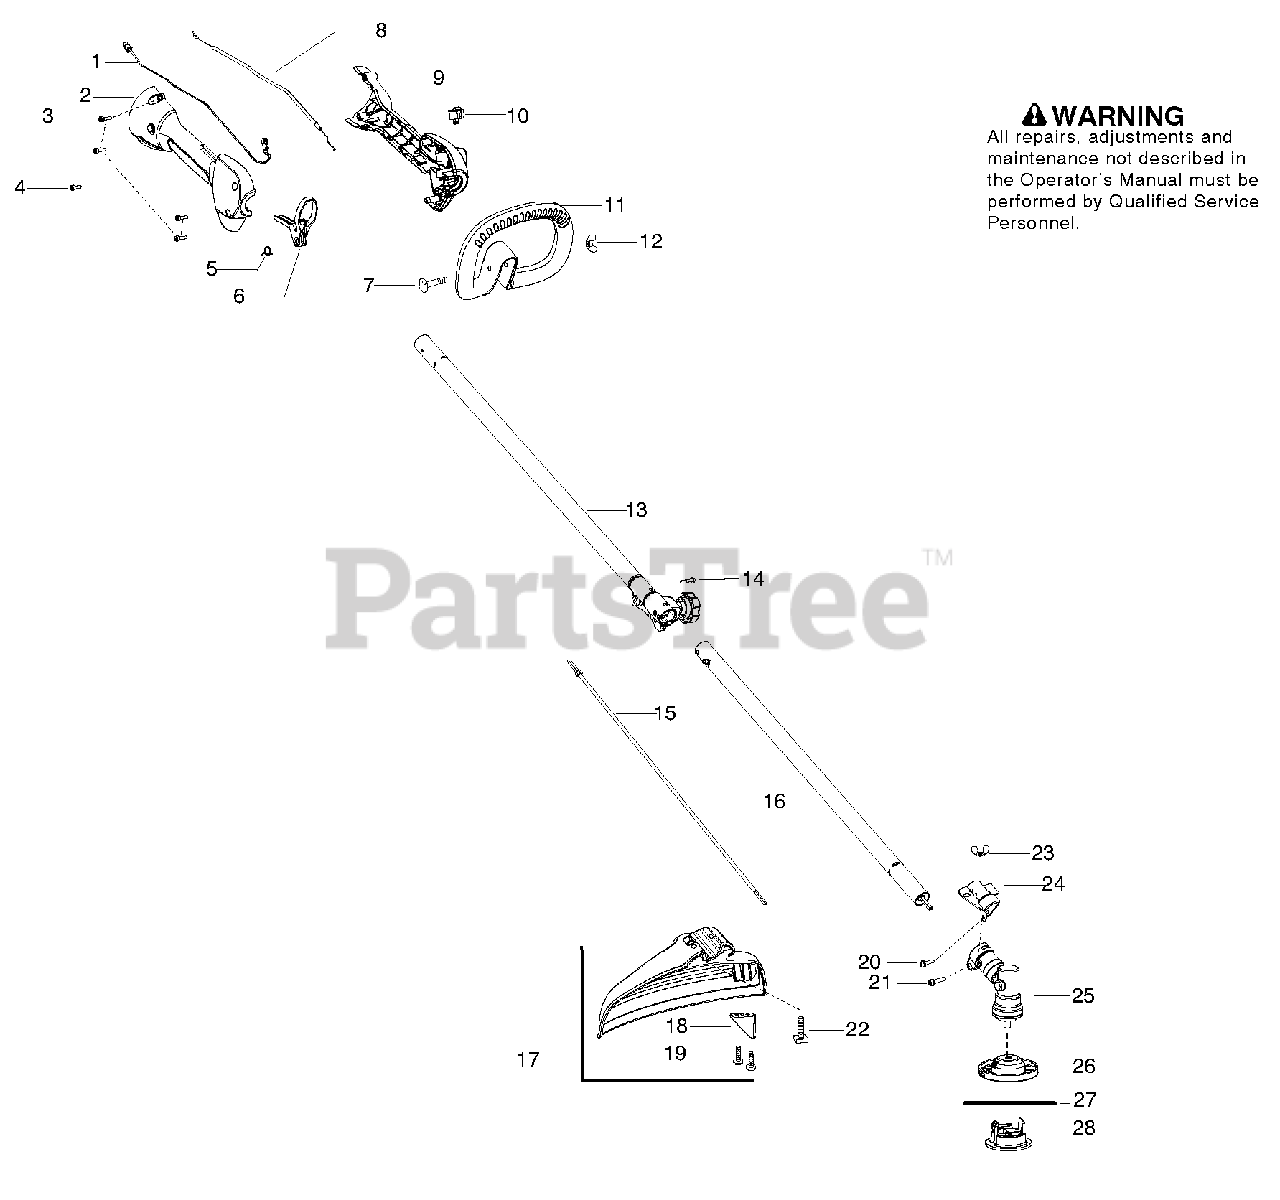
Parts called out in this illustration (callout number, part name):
1	Assy-Switch Wire
2	Housing-Throttle (RH)
4	Screw 10-14 x 1/2
5	Spring-Trigger
6	Kit - Trigger
7	Bolt -1/4-20 x 2
8	Assy - Throttle Cable
9	Housing-Throttle (LH)
10	Kit-Switch
11	Assy - Handle Assist
12	Wingnut - 1/4-20
13	Kit-Driveshaft Upper
14	Screw - 12-24 x 480
16	Kit-Driveshaft Lower
17	Kit-Shield
19	Screw - 10-14 x 3/4
20	Screw - 8-16 x .593
21	Screw - 12-24 x .960
22	Bolt - 1/4-20 x 1-1/4
23	Wingnut - 1/4-20
24	Bracket - Shield
25	Assy - Gearbox 1"
26	Assy - Fixed Line Head
27	Accy - Line (12 pcs )
28	Cap - Fixed Line
